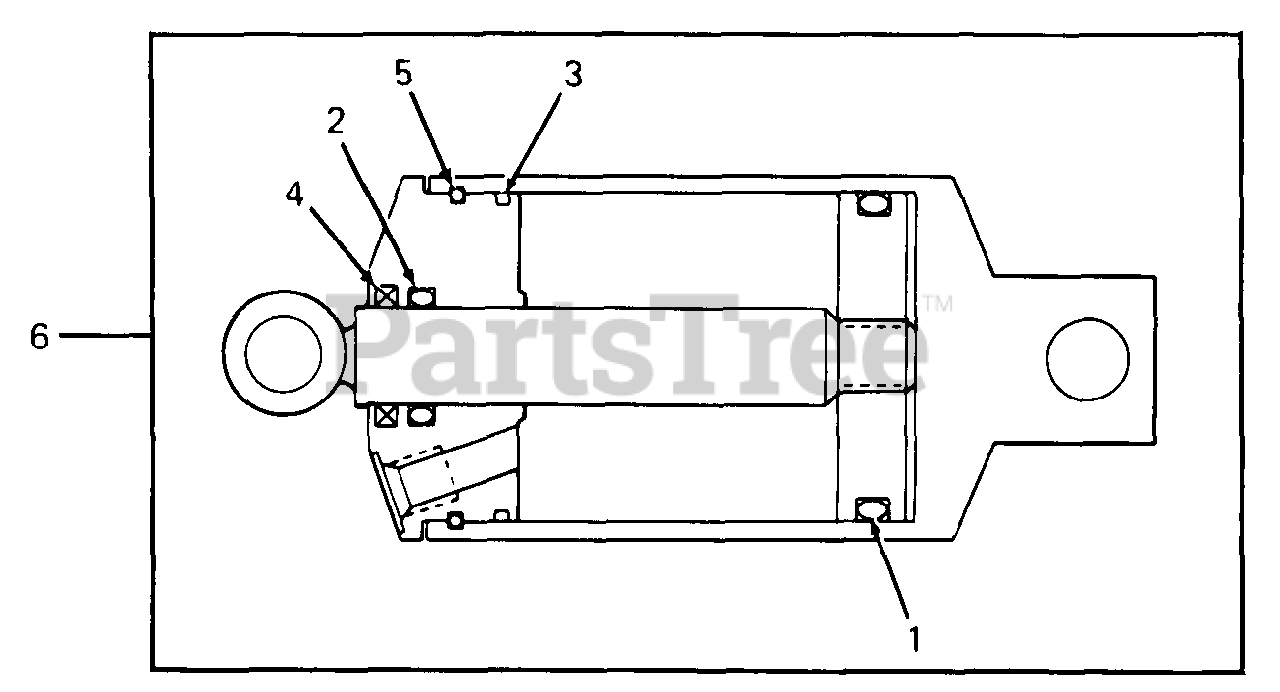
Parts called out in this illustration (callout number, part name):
4	Seal, Hydraulic Cylinder Piston Rod Wiper
5	Retainer, Hydraulic Cylinder Front Head
6	Cylinder, Hydraulic
